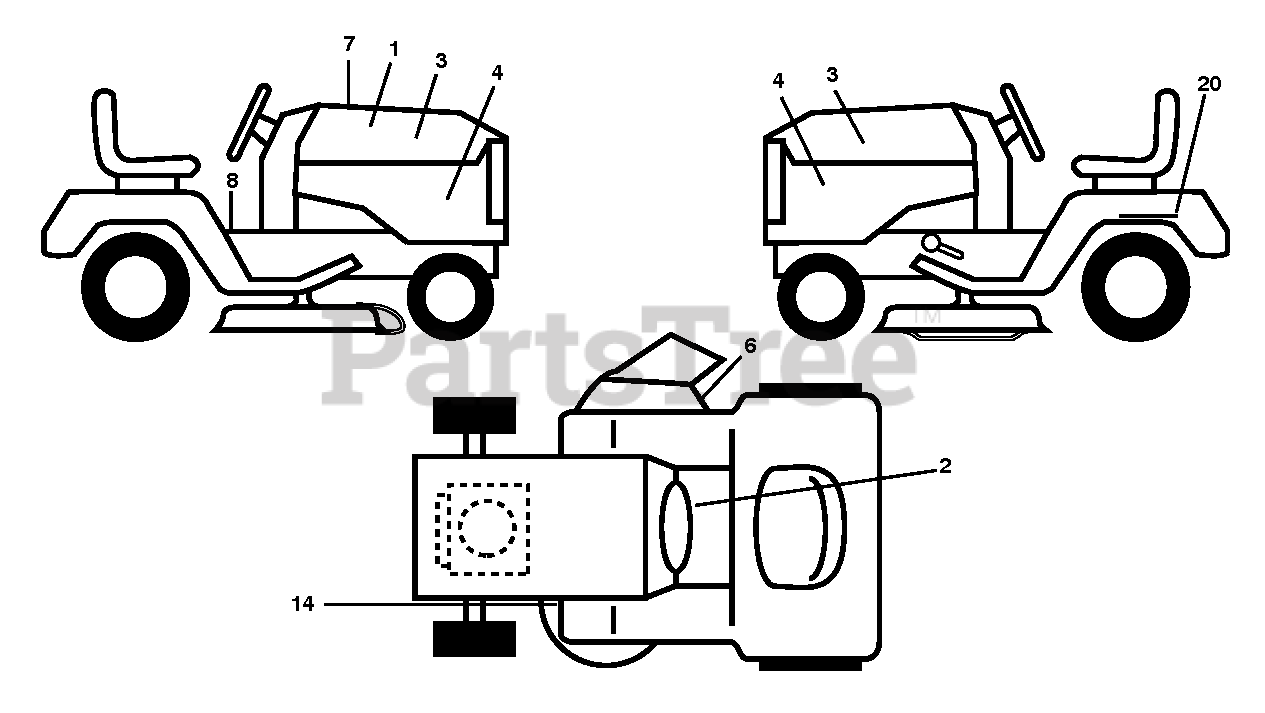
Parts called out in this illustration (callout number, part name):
1	DECAL.WARNING.CUST.RESP.E85.
2	DECAL, WARNING SPARK ARRESTOR
3	RP.DECAL.BADGE.170MM.TEXTLOGO
4	DECAL.SIDE.PANEL.YTA19K42
6	DECAL.WARN.KEEP.HAND.AWAY
7	DECAL.REPLACEMENT.YTA19K42
8	DECAL.FENDER.WARNING
14	DECAL V BELT SCHEMATIC
20	DECAL BTRY SYMBOLS
